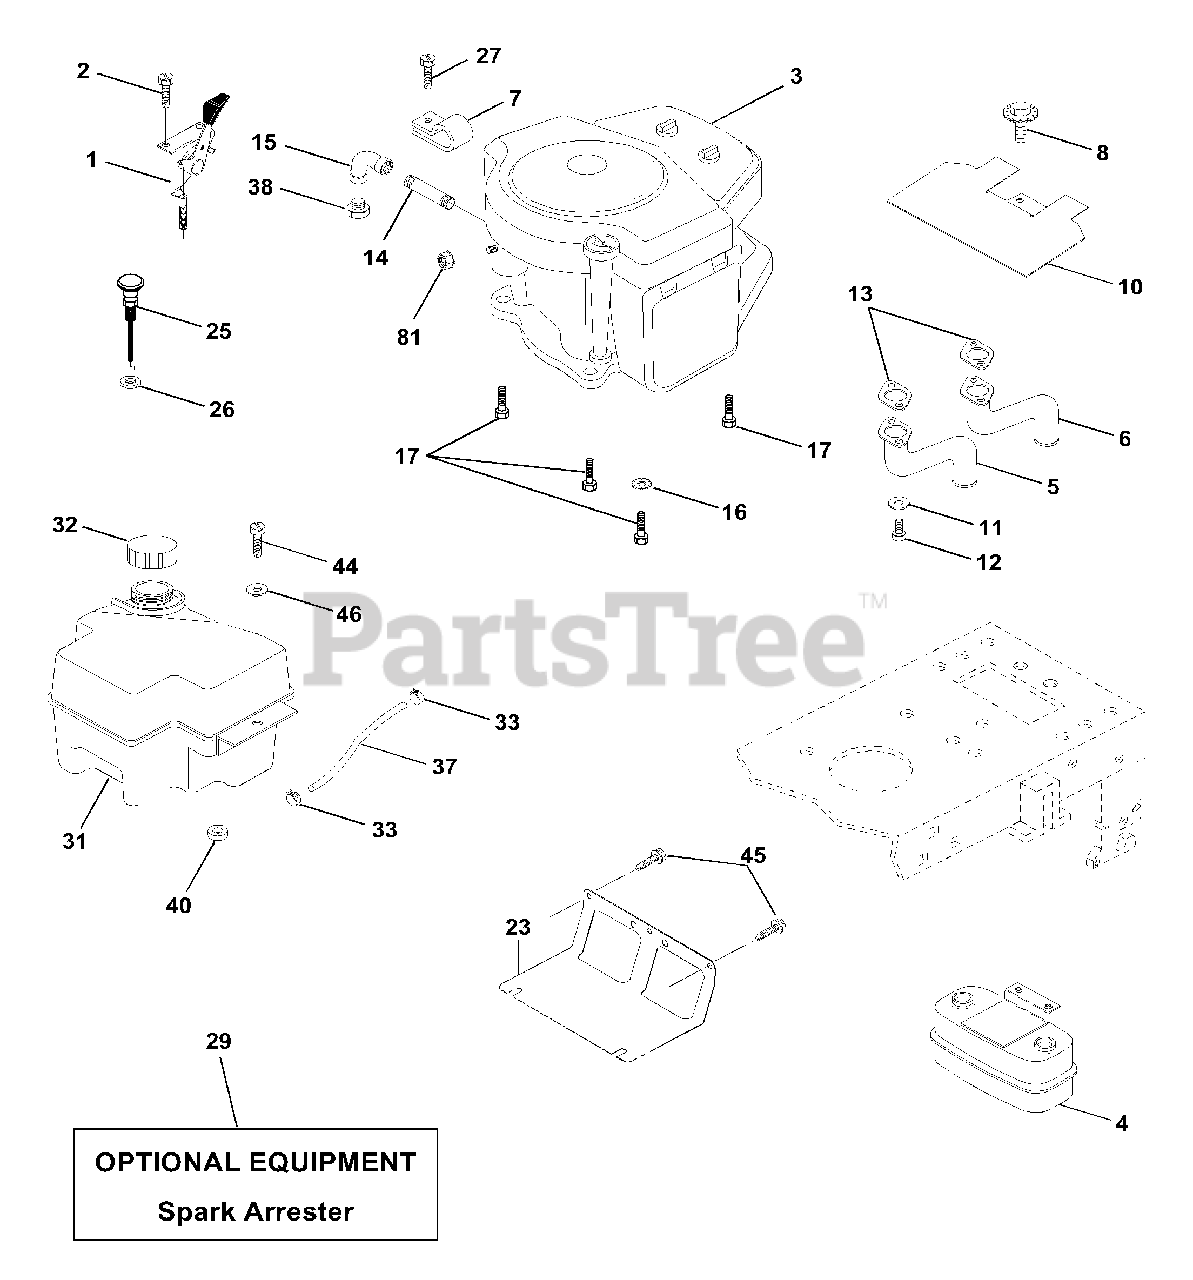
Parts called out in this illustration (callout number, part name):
1	Control Throt 35.5 Lh Flag
2	Screw Hex Thd Cut 1/4-20x5/8 T
4	Muffler Exhaust
5	Exhaust Asm. Left
6	Exhaust Asm. Right
7	Clamp Tube Double Engine
8	Bolt 5/16-18unc x 3/4 w/sems
10	Shield Heat
11	Wash Lock Hvy Hlcl spr 1/4
12	Bolt Fin Hex 1/4-20 x 3/4
13	Gasket Muffler
14	Nipple Pipe 4-12"
15	Elbow Std 90 Degree 3/8-18 Npt
16	Washer Lock Ext Tooth 3/8
17	Screw Thdrol 3/8-16 x 1-1/2 Tytt
23	Shield Brn/Dbr Guard
25	Control Choke
26	Nut Keps 3/8-24 UNF
27	Screw TT #10-32.5 3/8 Flange
29	Arrestor Spark
31	Tank Fuel Front 2.00
32	Cap Fuel
33	Clamp Hose Blk
37	Line Fuel
38	Plug Oil Drain
40	Bushing Snap Nyl Blk Fuel Line
44	Screw Hex wsh Thdrol 1/4-20 x 3/4
45	Screw Hex Wsh Thdr 3/8-16 x 3/4
46	Washer 9/32 x 7/8 x 16 Ga.
81	Nut Keps Hex 1/4-20 Unc
